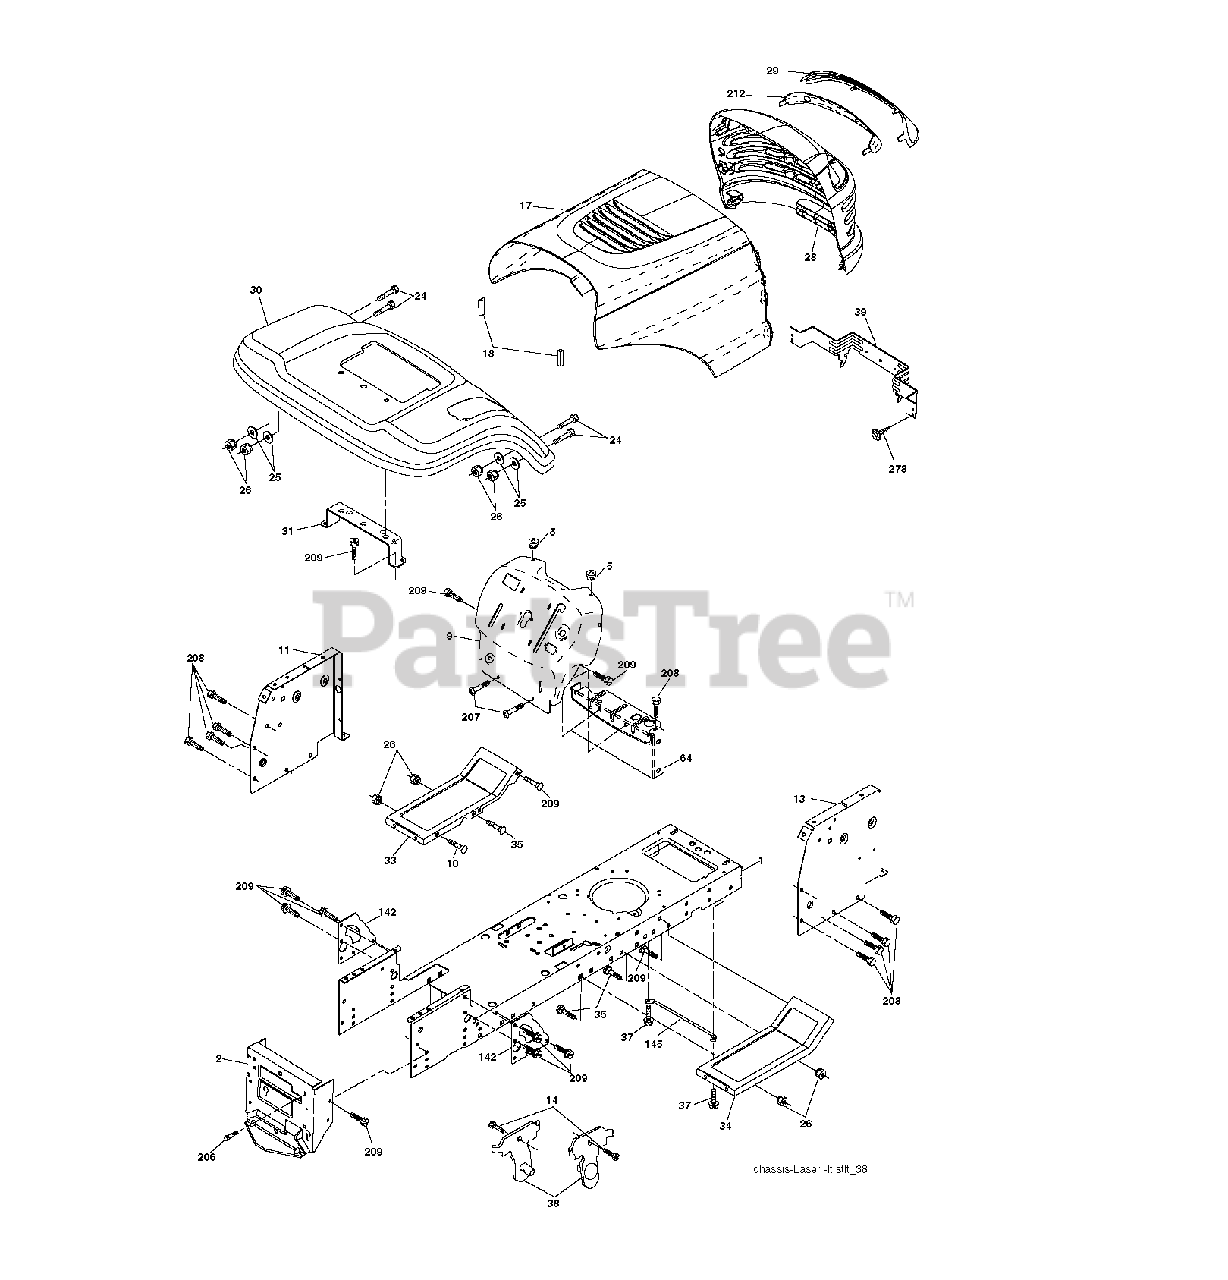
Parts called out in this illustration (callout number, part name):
1	CHASSIS STAMPING
2	DRAWBAR, 12GA
5	BUMPER.RUBBER.HOOD
10	BOLT D
11	PANEL.DASH.LH.LTX
14	SCREW LT
18	BUMPER.HOOD.LARGE.1.75"
24	BOLT
25	WASHER
26	NUT
31	BRACKET FENDER
35	BOLT
37	SCREW LT
38	BRACKET.ASM.PIVOT.MOWER.REAR
39	BRACKET PIVOT
64	DASH LOWER
142	PLATE REINFORCEMENT
145	ROD.PIVOT.HOOD
206	SHOULDER BOLT 5/16-18TT
207	SCREW, 5/16-18 X 1/2
208	SCREW 3/8-16X1/2
209	SCREW, 3/8-16X3/4
278	SCREW
